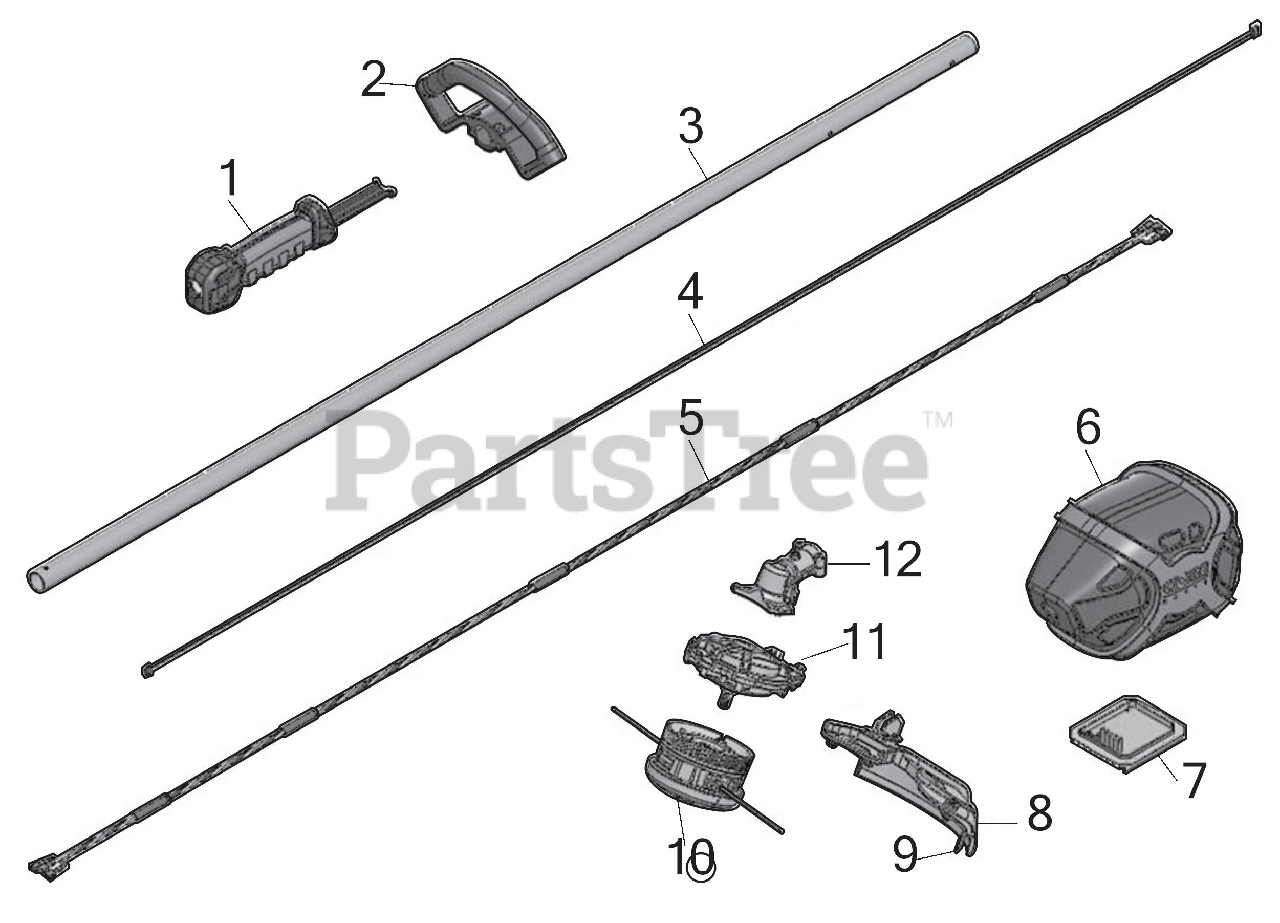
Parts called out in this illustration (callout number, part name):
1	GRIP ASSEMBLY W/WIRES E400 CORE
2	HANDLE ASSEMBLY CORE
3	BOOM E400 CORE
4	HARNESS HALL WIRE CGT400 CORE
5	HARNESS PHS WIRE CGT400 CORE
6	HOUSING ASSEMBLY PWR E400 CORE
7	CONTROLLER E400 CORE
8	GUARD/BLD ASSEMBLY E400 CORE
9	CUT OFF BLADE E400 CORE
10	BUMP HEAD ASSEMBLY E400 CORE
11	MOTOR ASSEMBLY E400 CORE
12	YOKE ASSEMBLY CGT400 CORE
